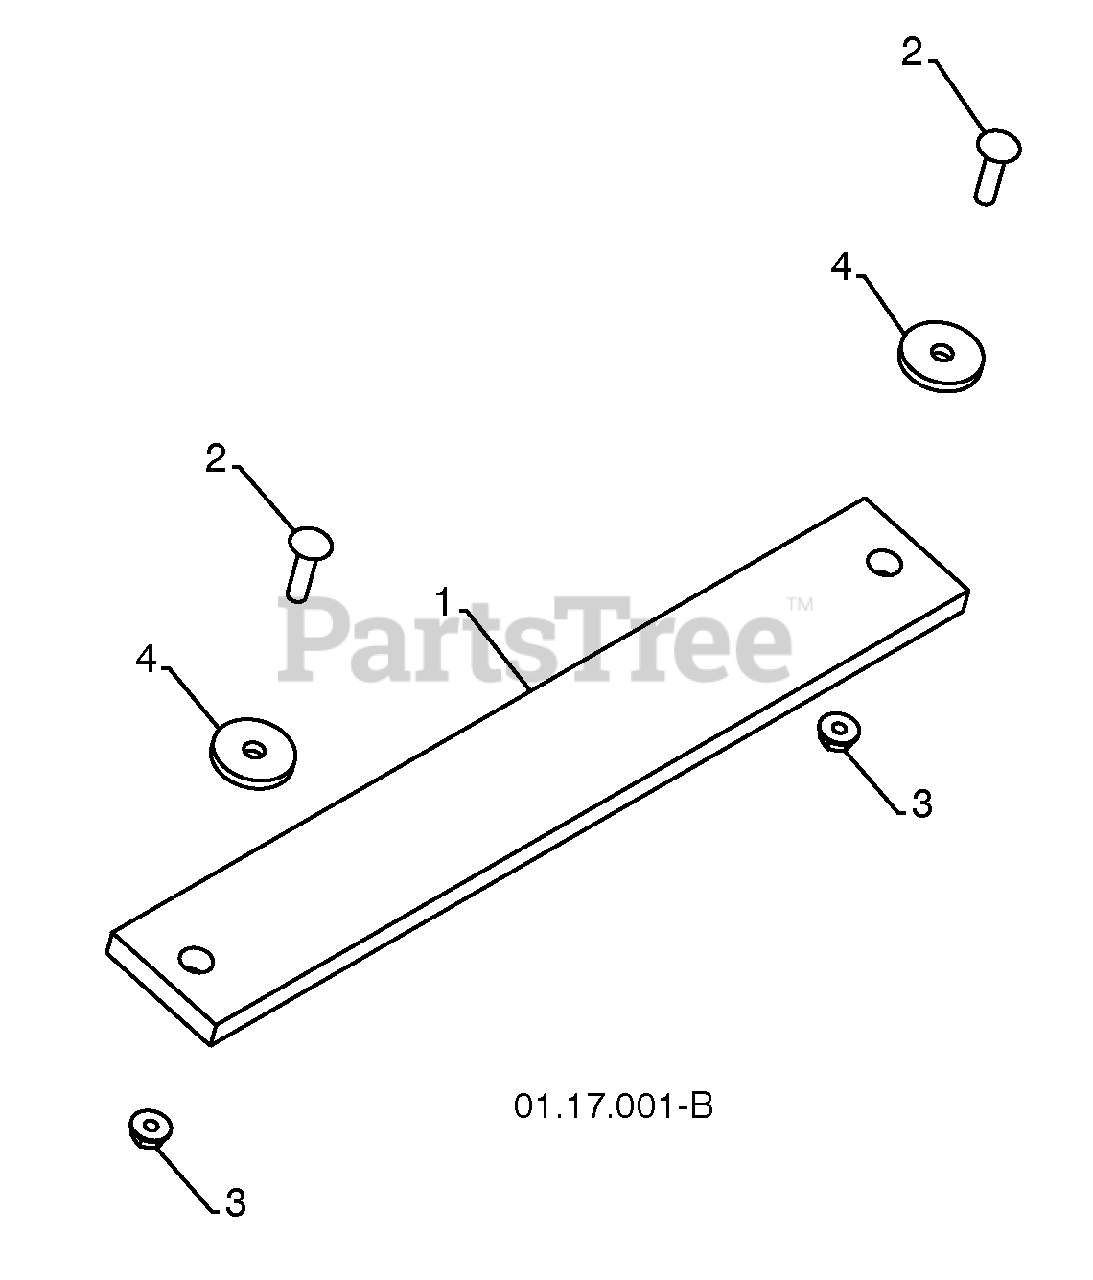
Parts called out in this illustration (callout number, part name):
1	WEIGHT BAR
2	CARRIAGE BOLT 5/16-18 X 1.25
3	NUT 5/16-18
